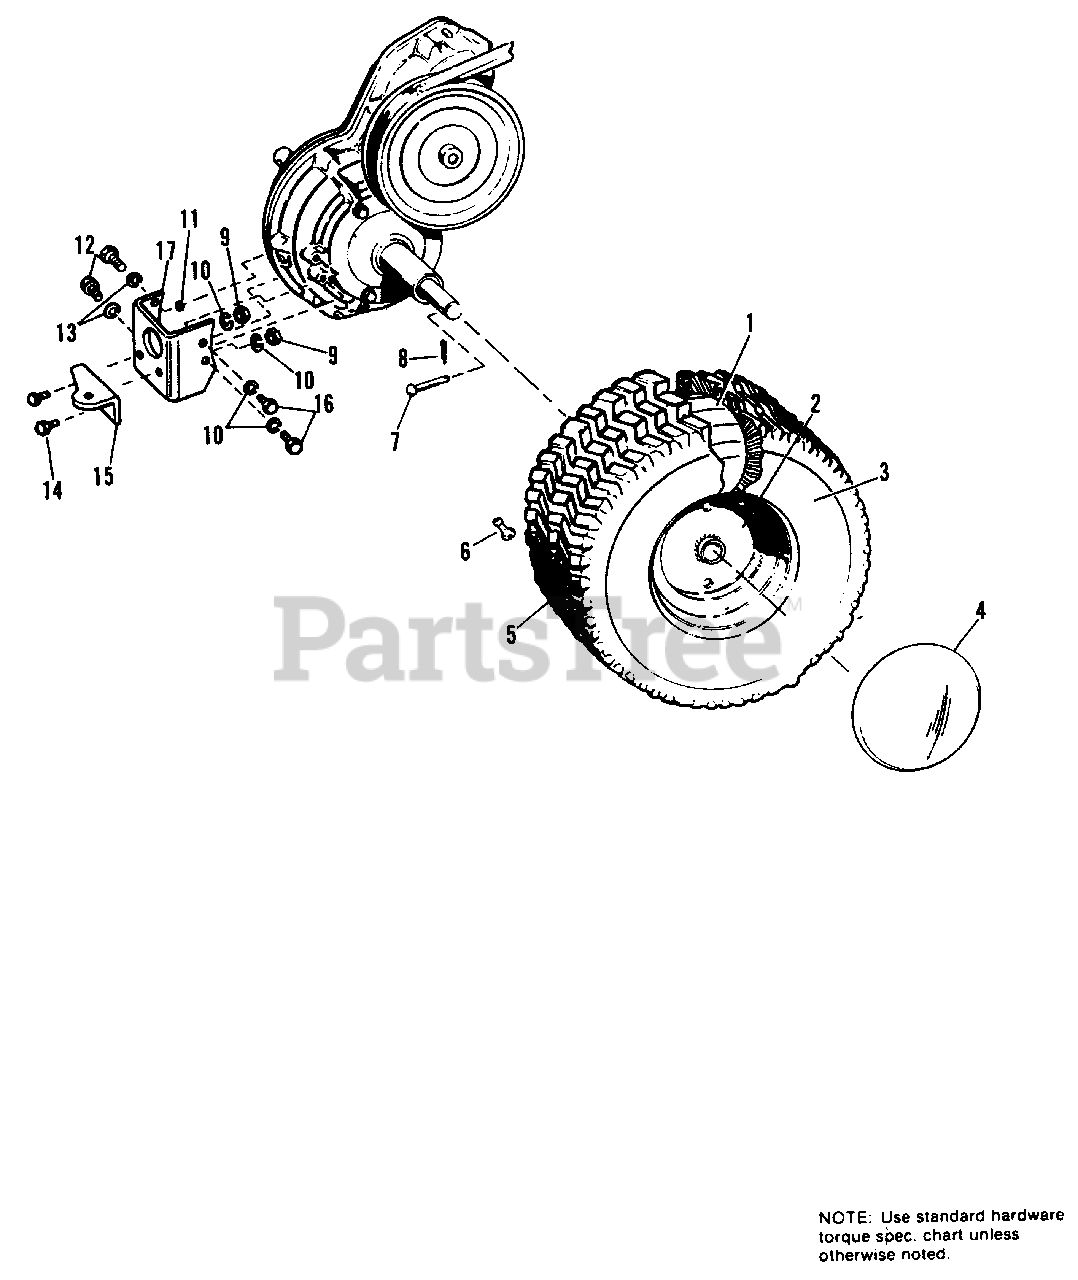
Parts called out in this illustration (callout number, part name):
1	TUBE (1690020 & 1690106 Only)
2	WHEEL ASSY. (1690020 & 1690106 Only)
2	WHEEL ASSY.
3	TIRE (1690020 & 1690106 Only)
4	HUB CAP, Rear
5	WHEEL & TIRE ASSY. (1690020 & 1690106 Only)
5	WHEEL & TIRE ASSY.
6	VALVE STEM & CAP
7	PIN
8	PIN, Cotter, 1/8 x 3/4
9	NUT, Hex, Full, 3/8-16
10	LOCKWASHER, 3/8
11	WASHER, Plain, 5/16
12	CAPSCREW, Hex Hd., 5/16-18 x 1-1/4
13	LOCKWASHER, 5/16
14	CAPSCREW, Hex Hd., 3/8-16 x 1
15	CLIP, Draw Bar Hitch
16	CAPSCREW, Hex Hd., 3/8-16 x 3/4
17	BRACKET, Draw Bar
18	BUTTON, Plug (990577, 990780 & 990904 Only)
